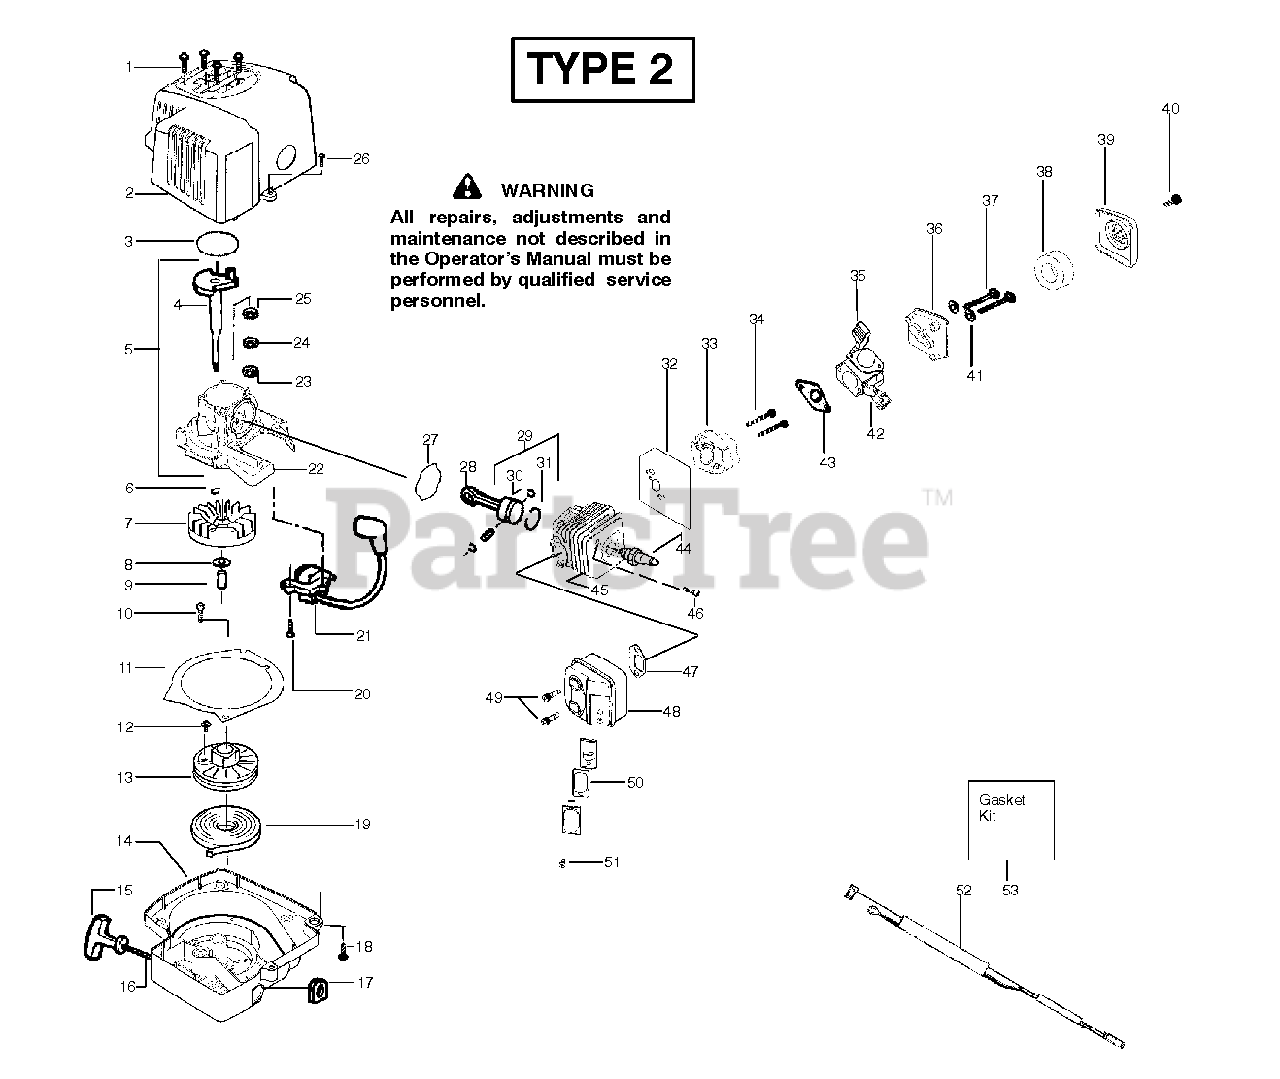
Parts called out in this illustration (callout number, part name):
2	ASSY SHROUD/HEAT SHIELD
3	GASKET KIT
4	CRANKSHAFT ASSY
5	CRANKCASE
6	RETAINING RING
7	FLYWHEEL
8	WASHER FLAT
10	SCREW-10-16 X 1/2 HI-LO
11	PLATE-BAFFLE
12	SCREW SEMS TOOTHED WASHER
13	STARTER PULLEY
14	ASSY FAN HSG W/ EYELET
15	HANDLE-STARTER
16	KIT-ROPE
18	SCREW
19	STARTER SPRING
21	IGNITION MODULE
22	CRANKCASE
23	OUTER BEARING
25	BEARING
27	GASKET KIT
28	KIT-CONN ROD ASSY
29	PISTON
30	WRIST PIN RET.
31	RING-PISTON
32	GASKET KIT
35	CHOKE CONTROL
38	AIR FILTER FOAM
39	AIR FILTER COVER
41	WASHER
42	CARBURETOR ASSY (C1U-W13A)
43	GASKET KIT
44	PLUG-SPARK (RCJ-6Y)
45	CYLINDER
47	GASKET KIT
49	SCREW MUFFLER
50	PARTITION
51	SCREW-6-19X5/16PLAST PA
52	LEAD WIRE
53	GASKET KIT
